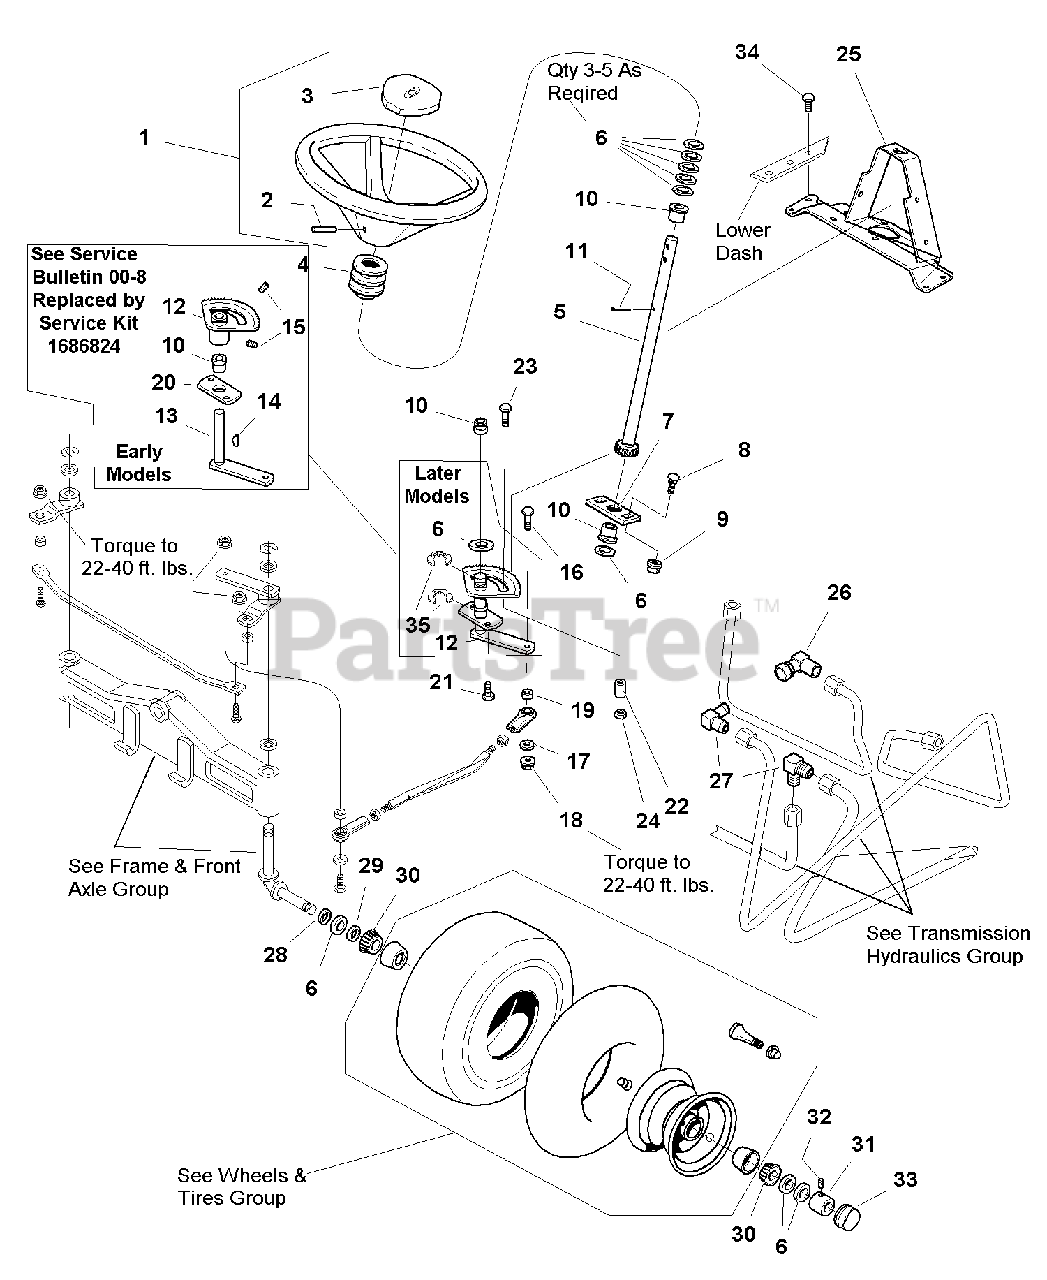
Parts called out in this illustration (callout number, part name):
1	STEERING WHEEL ASSEMBLY (Includes Ref. Nos. 2 and 3)
2	PIN, Spring, 5/8 x 2
3	CAP, Steering Wheel
4	TUBE, Steering
5	SHAFT ASSEMBLY, Steering (Manual)
6	WASHER, Plain, 3/4
7	PLATE, Mounting, Steering
8	CARRIAGE BOLT, 3/8-16 x 1
9	NUT, Hex Flange Whiz Lock, 3/8-16
11	PIN, Cotter, 3/16 x 1-1/4
12	GEAR ASSEMBLY, Steering (Early Models )(See Service Bulletin 00-8)
12	STEERING GEAR ASSEMBLY, (Later Models)
13	PITMAN ARM ASSEMBLY
14	KEY, Hi Pro
15	SETSCREW, Square Head, 5/16-18 x 1/2, G8
16	CAPSCREW, Hex Head, 3/8-16 x 1-3/8
17	WASHER, Plain, 3/8
18	NUT, Hex Flange, 2-Way Lock, 3/8-16
20	SECTOR MOUNTING PLATE
21	CAPSCREW, Hex Head, Taptite, 5/16-18 X 1
22	SPACER, Stop
23	CAPSCREW, Hex Head, 5/16-18 x 1-1/2
24	NUT, Hex Nylon Lock, 5/16-18
25	BRACKET & STEERING TOWER ASSEMBLY
26	FITTING, Hydraulic, 90 Degree Swivel Elbow (Hydraulic Lift Models Only)
27	FITTING, Hydraulic, 90 Degree Male (Hydraulic Lift Models Only)
30	BEARING, Tapered Roller
31	COLLAR, Set
32	SETSCREW, Square Head, 5/16-18 x 3/8, G8
33	CAP, Hub
34	CAPSCREW, Hex Head, Taptite, 1/4-20 x 1/2
35	CLIP RING, 3/4
